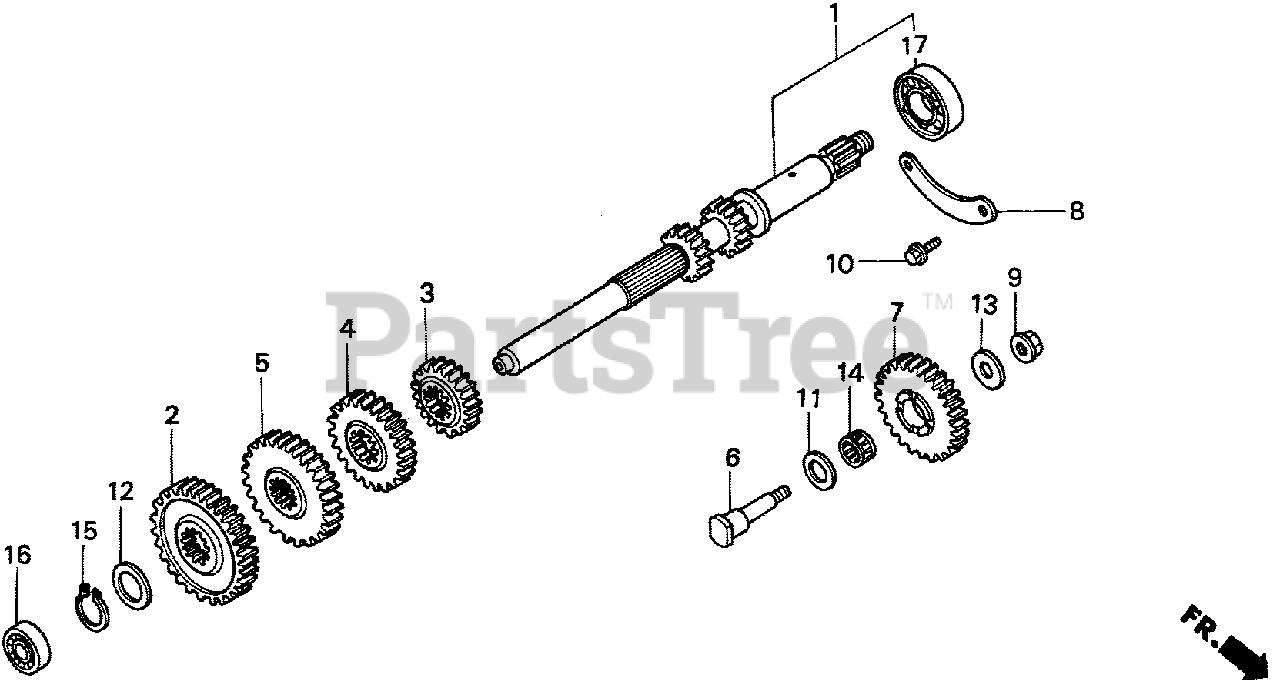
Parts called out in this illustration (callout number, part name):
2	GEAR, MAINSHAFT FIFTH (29T)
3	GEAR, MAINSHAFT SECOND (18T)
4	GEAR, MAINSHAFT THIRD (24T)
5	GEAR, MAINSHAFT FOURTH (27T)
6	SHAFT, REVERSE IDLE
7	GEAR, REVERSE IDLE (27T)
8	HOLDER, BEARING
9	NUT, SELF-LOCK (10MM)
10	BOLT, FLANGE (6X16)
11	WASHER, THRUST (15MM)
12	WASHER, THRUST (16MM)
13	WASHER, PLAIN (11MM)
14	BEARING, NEEDLE
15	CIRCLIP (OUTER) (16MM)
16	BEARING, RADIAL BALL (6001)
17	BEARING, RADIAL BALL (6004)
